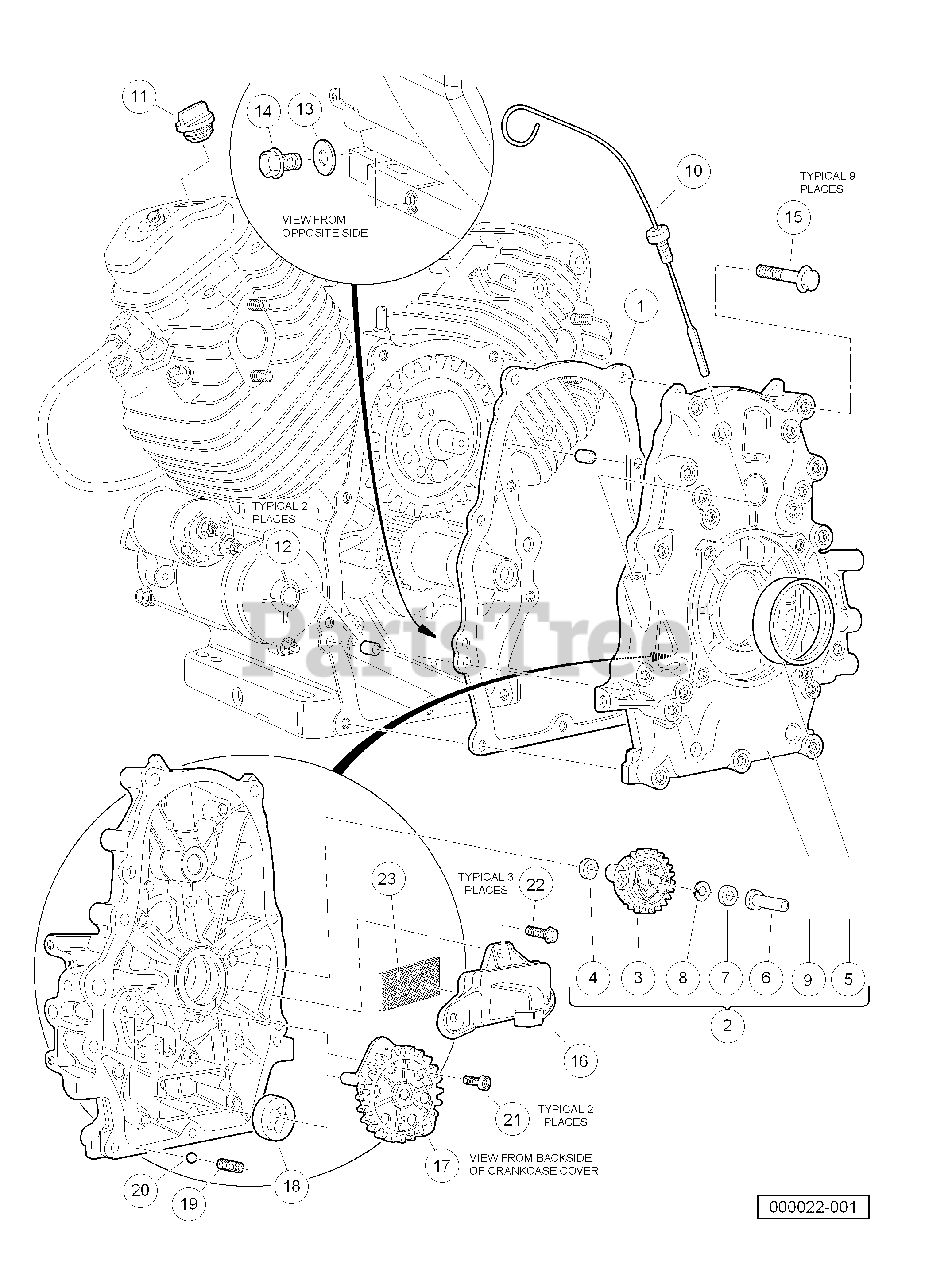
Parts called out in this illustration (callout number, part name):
1	Gasket, Case Cover
2	Cover Assembly, Crankcase
3	Governor Assembly
4	Washer, Plain, M6
5	Seal, Oil, 38 X 58 X 9
6	Slider, Governor
7	Washer, 6 X 16
8	Clip, Governor
9	Cover, Crankcase
10	Dipstick, Oil
11	Cap, Oil Filler
12	Pin A, Dowel, 8 X 14
13	Washer, Drain Plug, M14
14	Bolt, Drain Plug , M14
15	Bolt, Flange Head, M8 X 1.25 X 50
16	Cover, Oil Filter
17	Cover Assembly, Oil Pump
18	Rotor, Oil Pump, Outer
19	Spring, Relief Valve
20	Ball, Steel , 3/8, #12
21	Bolt, Socket
22	Bolt, Flange Head, M6 X 1 X 20
23	Screen, Oil Filter
